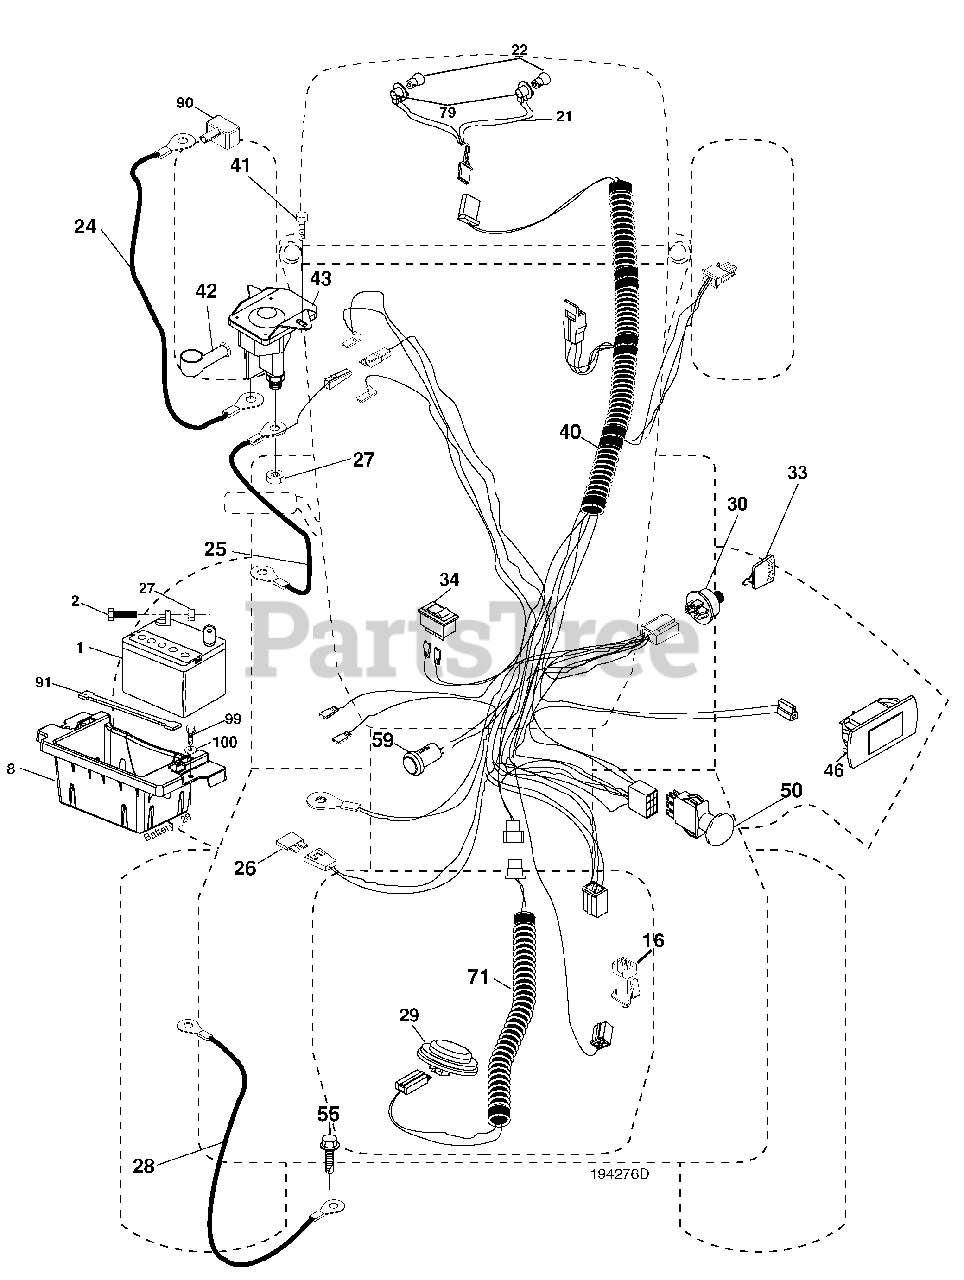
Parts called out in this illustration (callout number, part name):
1	Battery
2	Bolt Hex Head 1/4-20 x 3/4
8	Box Battery
16	Switch Interlock Push-In
21	Harness Socket Light W/4152J
22	Bulb Light
24	Cable Battery
25	Cable Start Red
26	Fuse
27	Nut Keps Hex 1/4-20 unc
28	Cable, Ground
29	Switch, Seat
30	Switch, Ignition
33	Key, Ignition
34	Switch Light / Reset
40	Harness Ignition
41	Screw Thd Cut 1/4-20 x 1/2
42	Cover, Terminal
43	Solenoid
46	Gauge Hourmeter
50	Switch, PTO
55	Screw Thdrol 5/16-18 x 3/4 TYTT
59	Outlet 12-Volt
71	Harness Ign. Dash
79	Bulbholder Asm. Incan Descent
90	Cover Terminal Battery
91	Strap Battery Mount Front
99	Screw Hexwsh Thdrol 1/4-20 x 3/4
100	Washer 9/32 x 7/8 x 16 Ga.
100	Harness Pigtail Trans.
